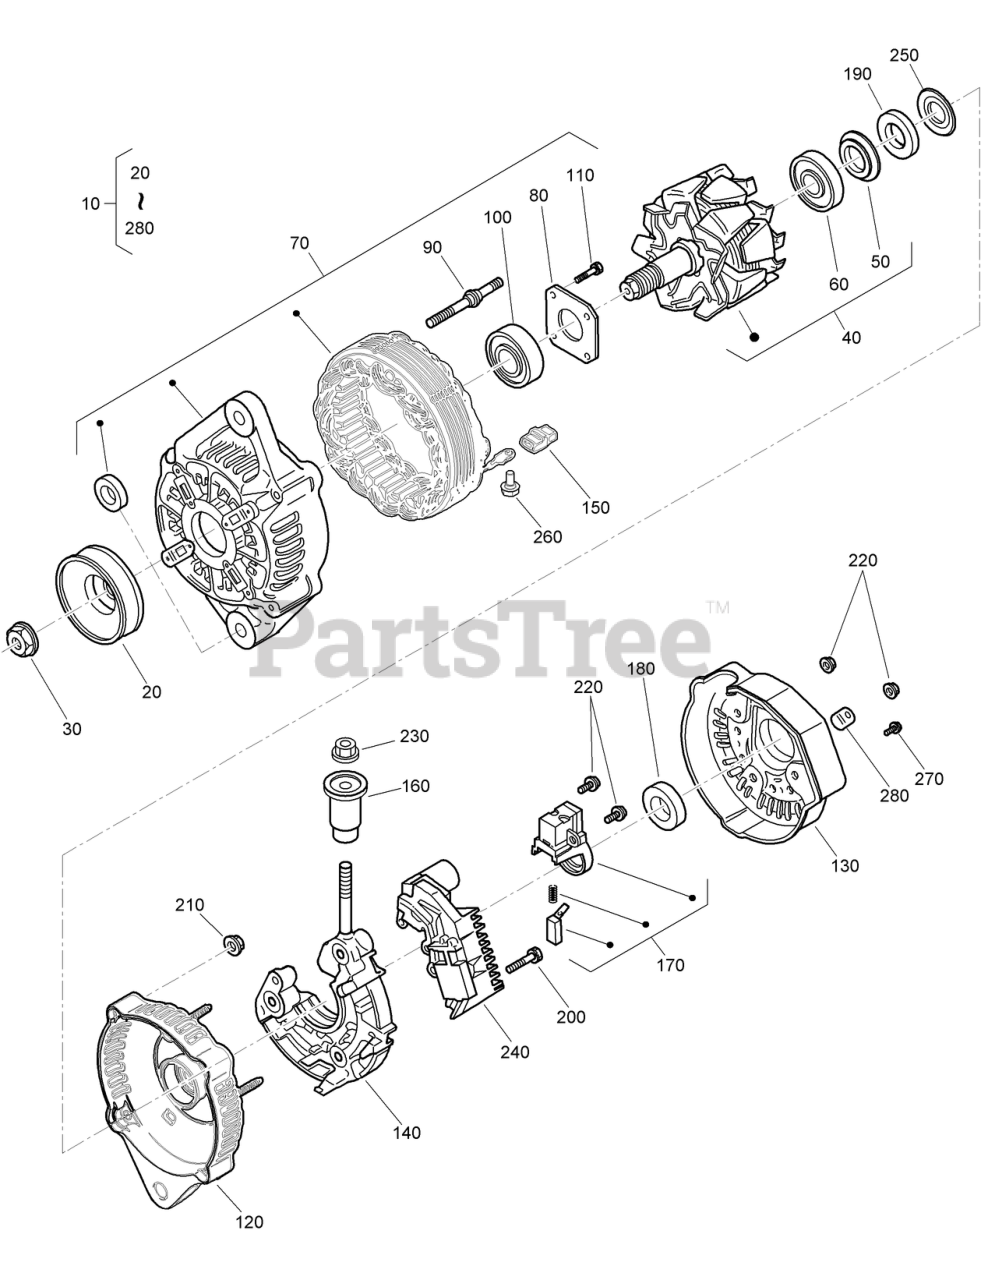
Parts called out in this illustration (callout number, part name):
10	ALTERNATOR ASM
20	PULLEY-ALTERNATOR
40	ROTOR ASM
50	COVER-BEARING
60	BEARING-BALL
70	DRIVE END FRAME ASM
80	PLATE-RETAINER
90	BOLT-THROUGH
100	BEARING-BALL
120	FRAME-END
130	COVER-END, REAR
140	RECTIFIER ASM
150	BUSHING-INSULATION
160	BUSHING-INSULATION
170	HOLDER-BRUSH
180	RING-SEAL
190	RING-SEAL
200	SCREW-HEAD, ROUND
220	SCREW-HEAD, ROUND
240	REGULATOR ASM
250	WASHER
260	SCREW-HEAD, ROUND
270	SCREW-HEAD, ROUND
280	PLATE-TERMINAL
